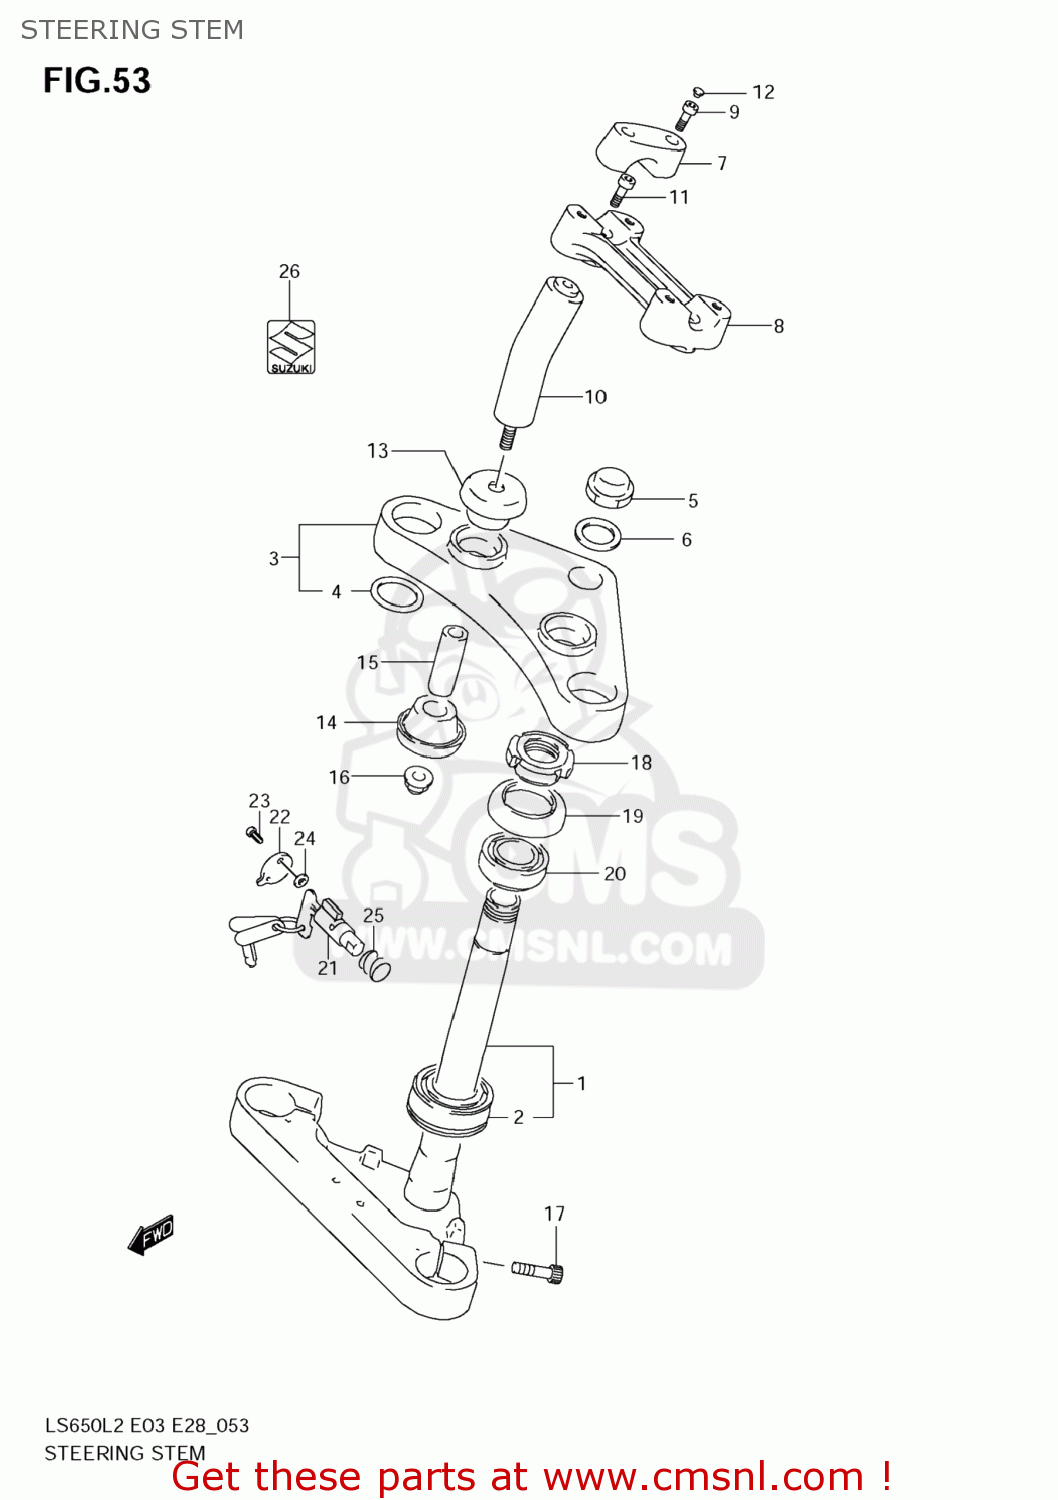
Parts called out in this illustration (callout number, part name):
1	STEM,STEERING
2	BEARING(30X55X17)
3	HEAD,STEERING STEM
4	WASHER,STEM HEAD,LOWER
5	NUT,CAP
6	WASHER(22.5X32X1.6)
7	HOLDER,HANDLE UPR
8	HOLDER,HANDLE LWR
9	BOLT
10	ARM
11	BOLT
12	CAP(OD:14.5)
13	CUSHION,UPR
14	CUSHION,LWR
15	SPACER(10.2X14X46)
16	NUT
17	BOLT
18	NUT,STEERING STEM(25X44X10)
19	SEAL,STEERING UPR DUST
20	BEARING(25X47X15)
21	LOCK ASSY,STEERING
22	CAP,STEERING LOCK
23	PIN,STEERING LOCK
24	WASHER,STEERING LOCK
25	SPRING,STEERING LOCK
26	EMBLEM,S
